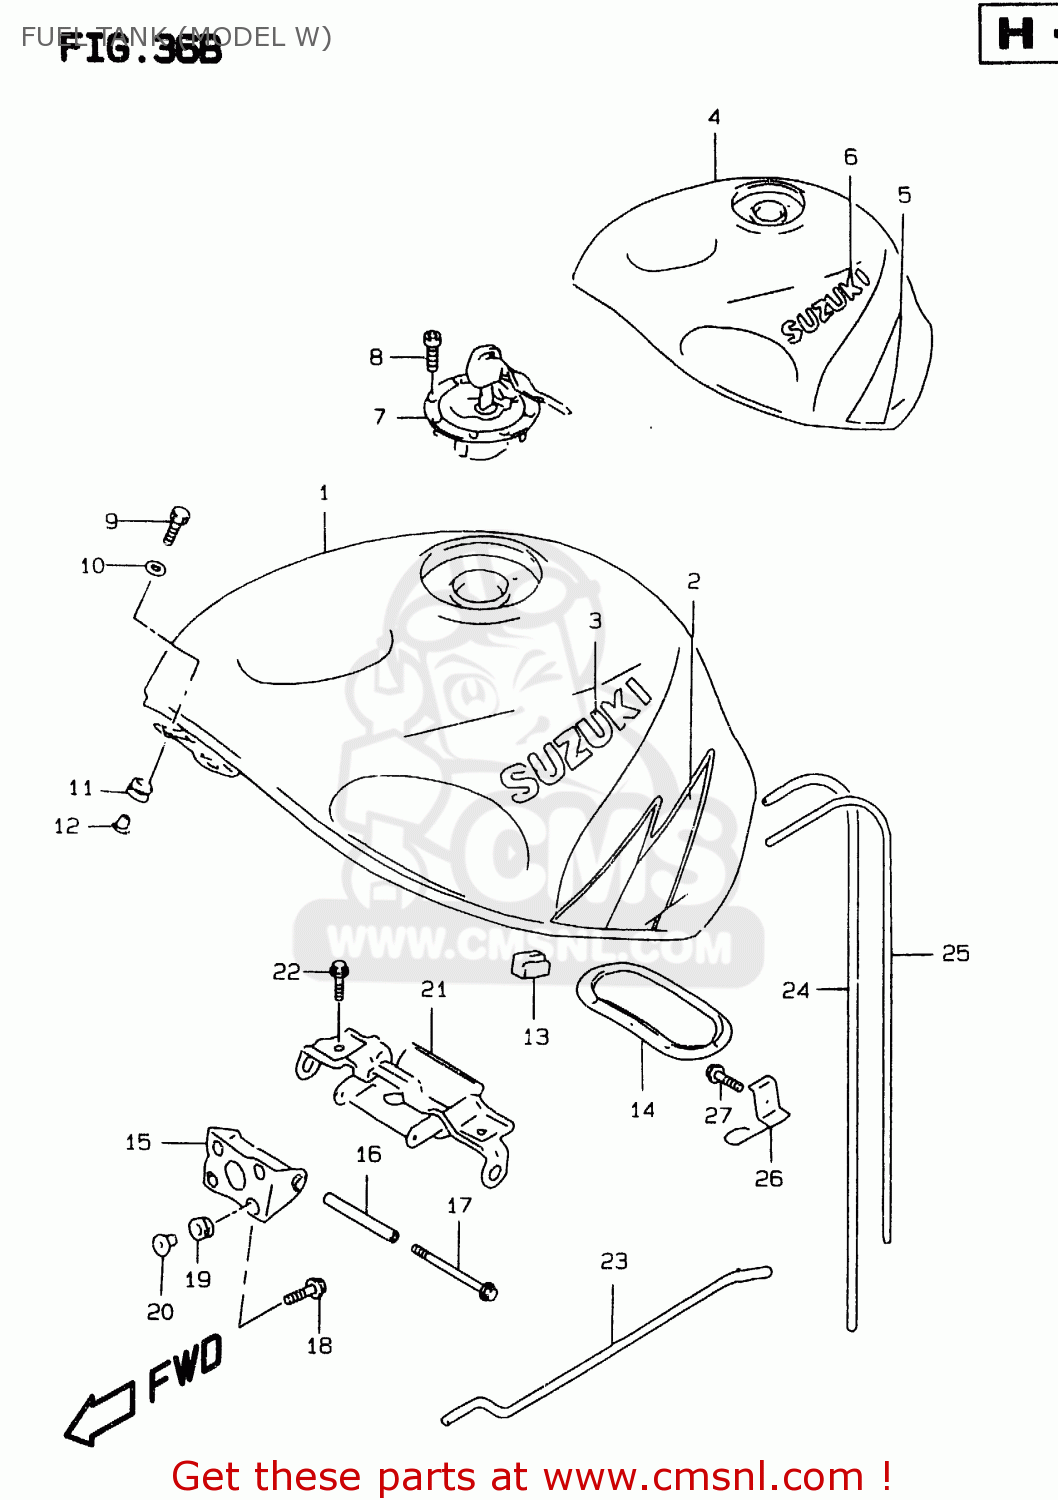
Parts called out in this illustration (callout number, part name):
1	TANK ASSY,FUEL
2	TAPE SET, TANK
3	EMBLEM,FUEL TANK
4	TANK ASSY,FUEL
5	TAPE SET,FUEL TANK
6	EMBLEM,FUEL TANK
7	CAP SET,FUEL TANK
8	BOLT(5X20)
9	SCREW(6X25)
10	WASHER(6.5X18X1.6)
11	CUSHION
12	WASHER
13	CUSHION,FUEL TANK SIDE
14	PACKING,FUEL PUMP (NAS)
15	BRACKET COMP,FUEL TANK
16	SPACER,FUEL TANK RR
17	BOLT
18	BOLT 6X20,WITH PLAIN WASHER
19	CUSHION
20	WASHER
21	BRACKET,FUEL TANK NO.2
22	BOLT
23	STAY,FUEL TANK
24	HOSE(5X8.2X600)
25	HOSE(7X10.2X600)
26	GUIDE COMP,DRAIN HOSE
27	BOLT
